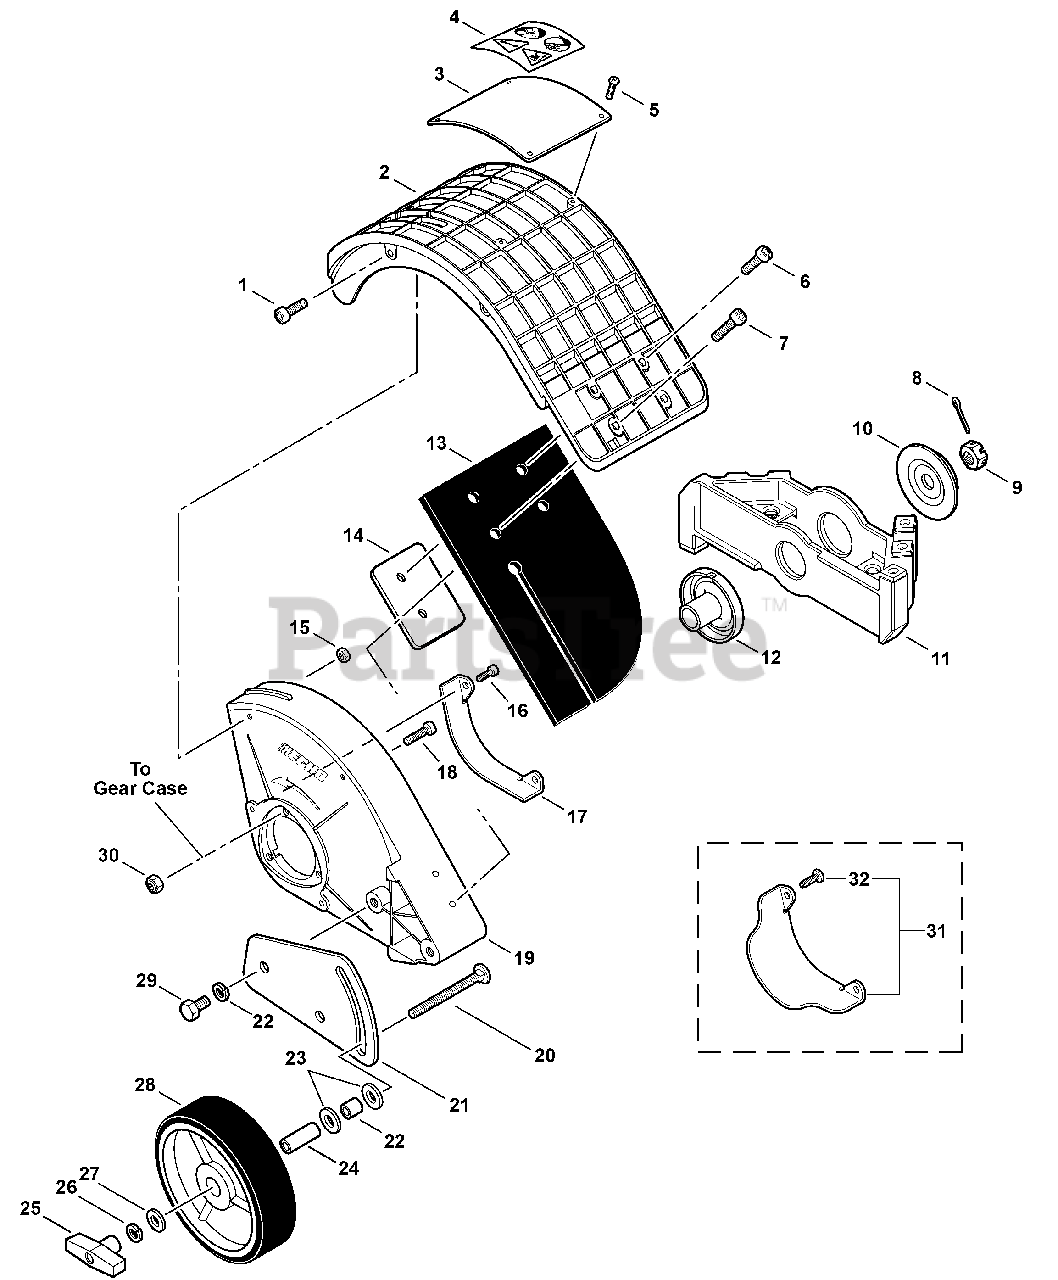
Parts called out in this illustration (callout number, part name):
1	BOLT, TORX 4×12
2	SHIELD, DEBRIS
4	LABEL, CAUTION
6	BOLT, TORX 4×12
7	BOLT, TORX 4×16
8	PIN, COTTER 2×22
9	NUT 10×1.25 LH
10	PLATE, ADAPTOR - LOWER
11	BLADE, REDEFINER
12	PLATE, ADAPTOR - UPPER
13	FLAP, DEBRIS
14	PLATE, FLAP
15	NUT, LOCK 4
16	BOLT, TORX 4×12
17	GUARD, SHIELD
18	BOLT, TORX 5×20
19	SHIELD, BLADE
20	BOLT 5/16"-18×3"
21	BRACKET, WHEEL
22	COLLAR 8
23	WASHER, SPRING 10
24	COLLAR 12
25	KNOB, FASTENER
26	WASHER, SPRING 8
28	WHEEL
29	BOLT 8×14
30	NUT, LOCK M5
31	GUARD KIT, SHIELD
32	SCREW 4×12
